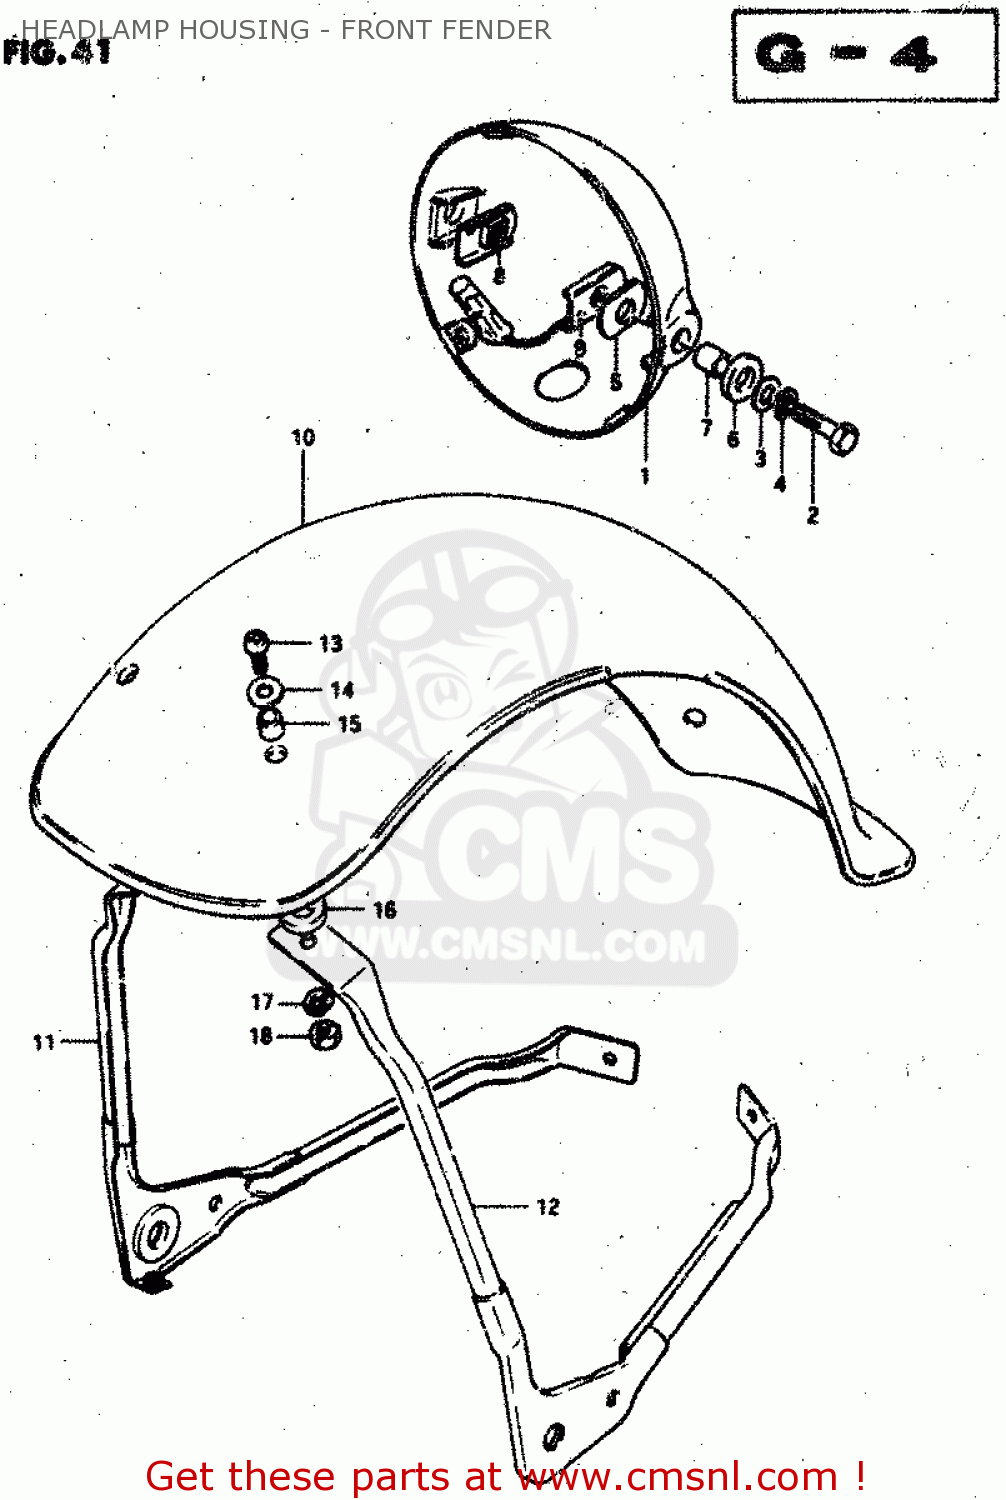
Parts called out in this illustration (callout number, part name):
1	HOUSING, HEADLAMP
2	BOLT (8X30)
3	WASHER
4	LOCK WASHER
5	CUSHION
6	CUSHION
7	SPACER (8.8X12X11)
8	PLATE,HEADLAMP HOUSING
9	PLATE,HEADLAMP HOUSING
10	FENDER, FRONT
11	BRACE, FRONT FENDER RH
12	BRACE, FRONT FENDER LH
13	SCREW
14	WASHER
15	SPACER (5.5X9.5X6.5)
16	CUSHION
17	LOCK WASHER
18	NUT
